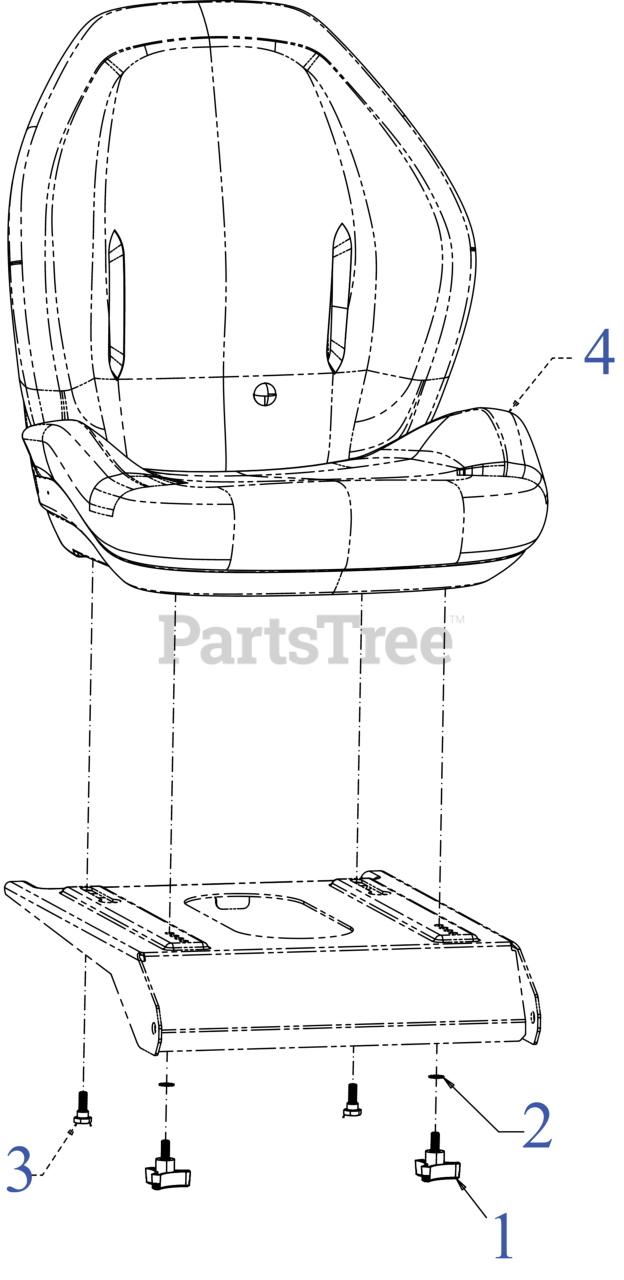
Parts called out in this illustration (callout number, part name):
1	3 PRONG KNOB 5/16-18
3	SHOULDER SCREW .437 DIA x .265
4	20.85" SEAT (4 PT MTG)
